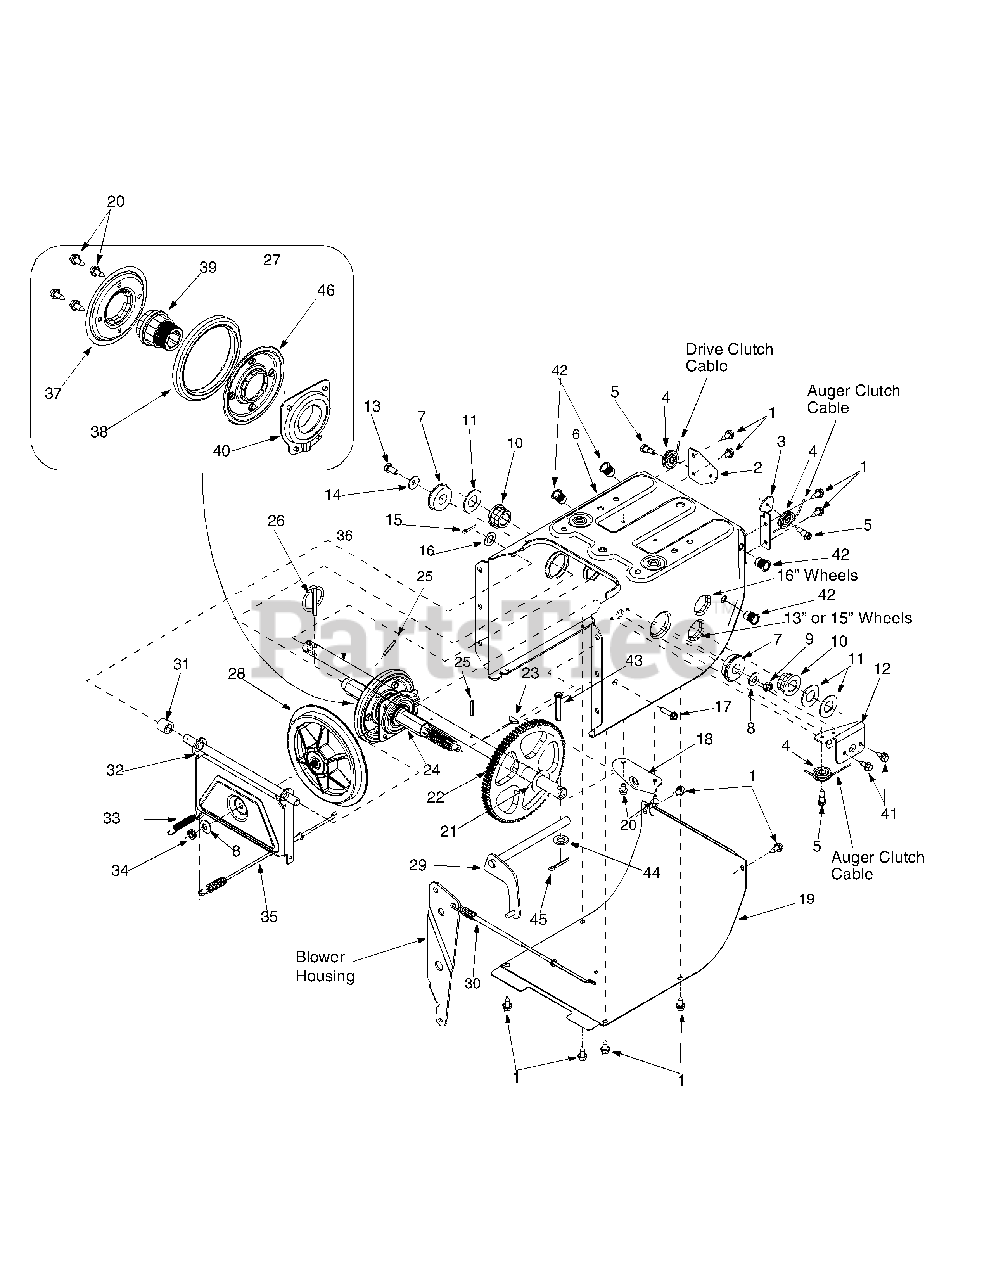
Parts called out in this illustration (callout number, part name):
1	Hex Screw
5	Hex Screw 1/4-28
6	Frame Assembly
7	Ball Bearing
8	Bell Washer
9	Lock Jam Nut
10	Hex Flange Bearing
11	Flat Washer
14	Bell Washer .340 ID x .872 OD
15	Cotter Pin
16	Flat Washer .536 ID x .930 OD
17	Hex Washer Screw 1/4-20
21	Flat Washer .760 ID x .50 OD
24	7-Tooth Shaft
25	Roll Pin
26	Klik Pin
27	Friction Wheel Assembly
28	Friction Disc Wheel
29	Wheel Shift Rod Assembly
30	Drive Cable
31	Spacer
34	Jam Nut 3/8-24
35	Drive Cable
36	Axle 13" Wheels
36	Axle 16" Wheels
37	Friction Plate
38	Friction Wheel Rubber
39	Friction Wheel Hub
40	Friction Wheel Bearing
41	Tap Screw 1/4-20
42	Insert Nut 5/16-18
43	Clevis Pin
44	Flat Washer .281 ID x .50 OD
45	Cotter Pin
46	Friction Plate
